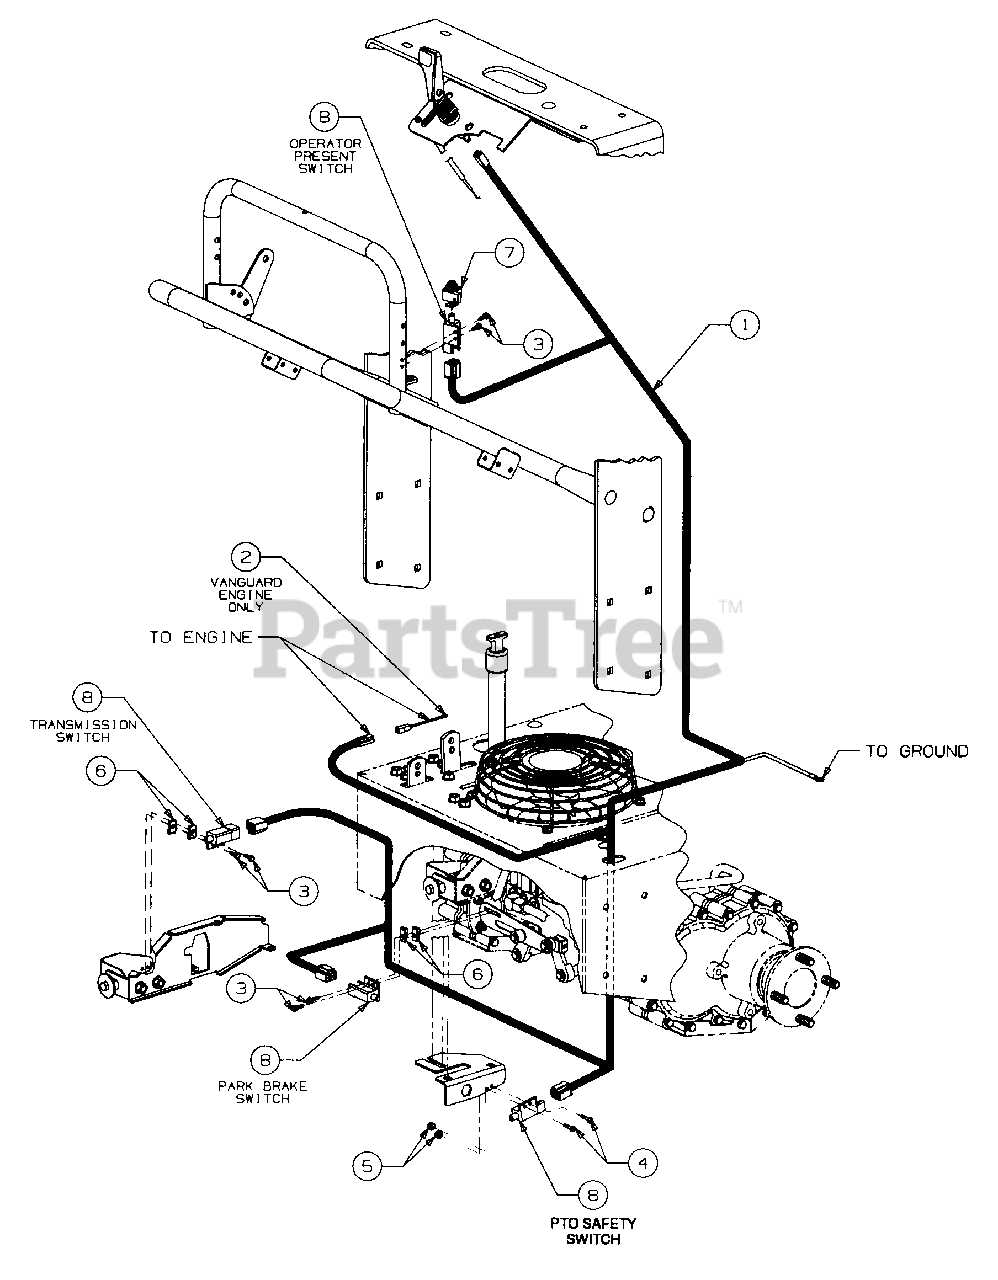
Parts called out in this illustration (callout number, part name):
2	Harness Adapter
3	Screw, Hex Wash Hd Tapp, #10-24 X .62 Lg
4	Screw, Pan Hd, #10-24 X .75 Lg
5	Nut, Hex Nylock, #10-24
6	Nut, Speed
7	Cover, Protective
8	Switch, Double Poled Plunger
